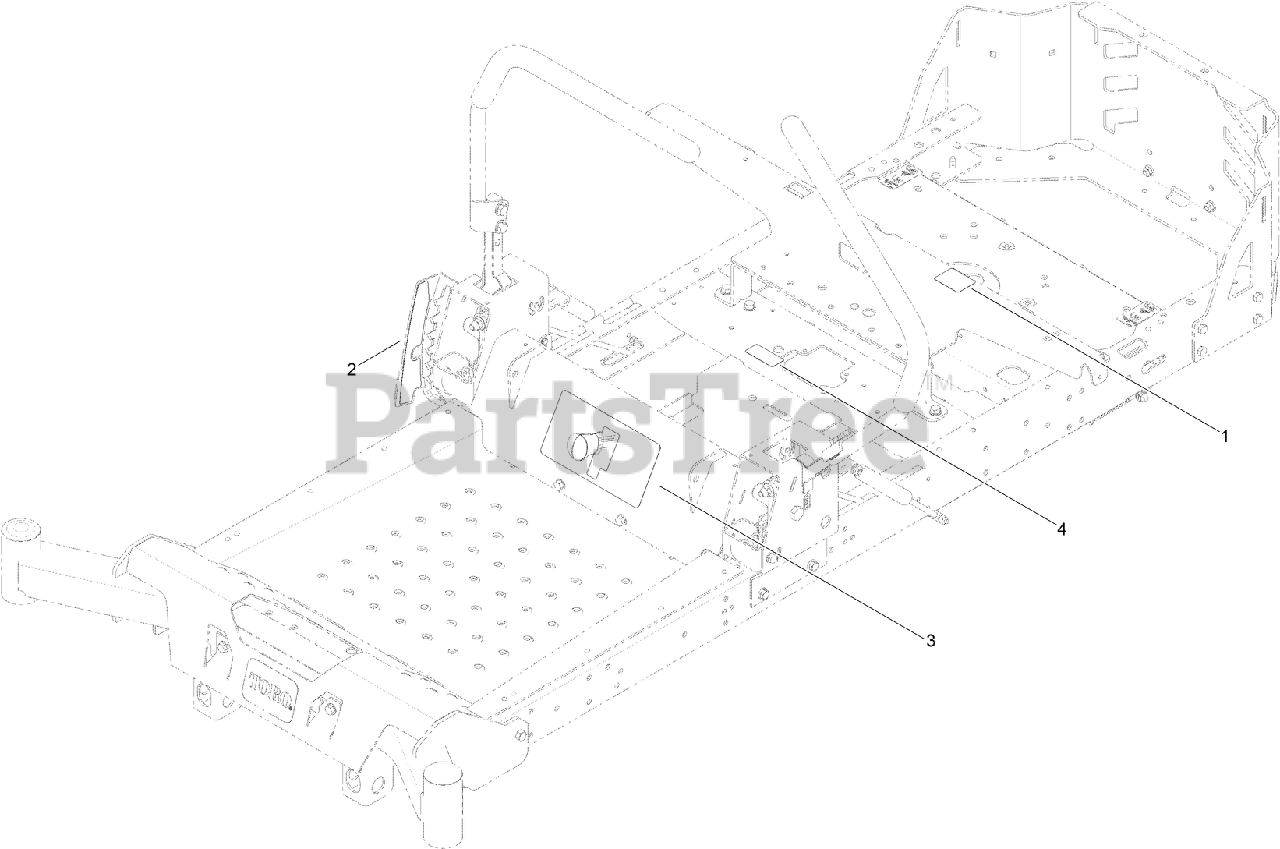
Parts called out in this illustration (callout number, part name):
1	DECAL-MAINTENANCE
2	DECAL-HOC
3	DECAL-CONTROL, SPEED
4	DECAL-LOCATION, SERVICE DEALER
